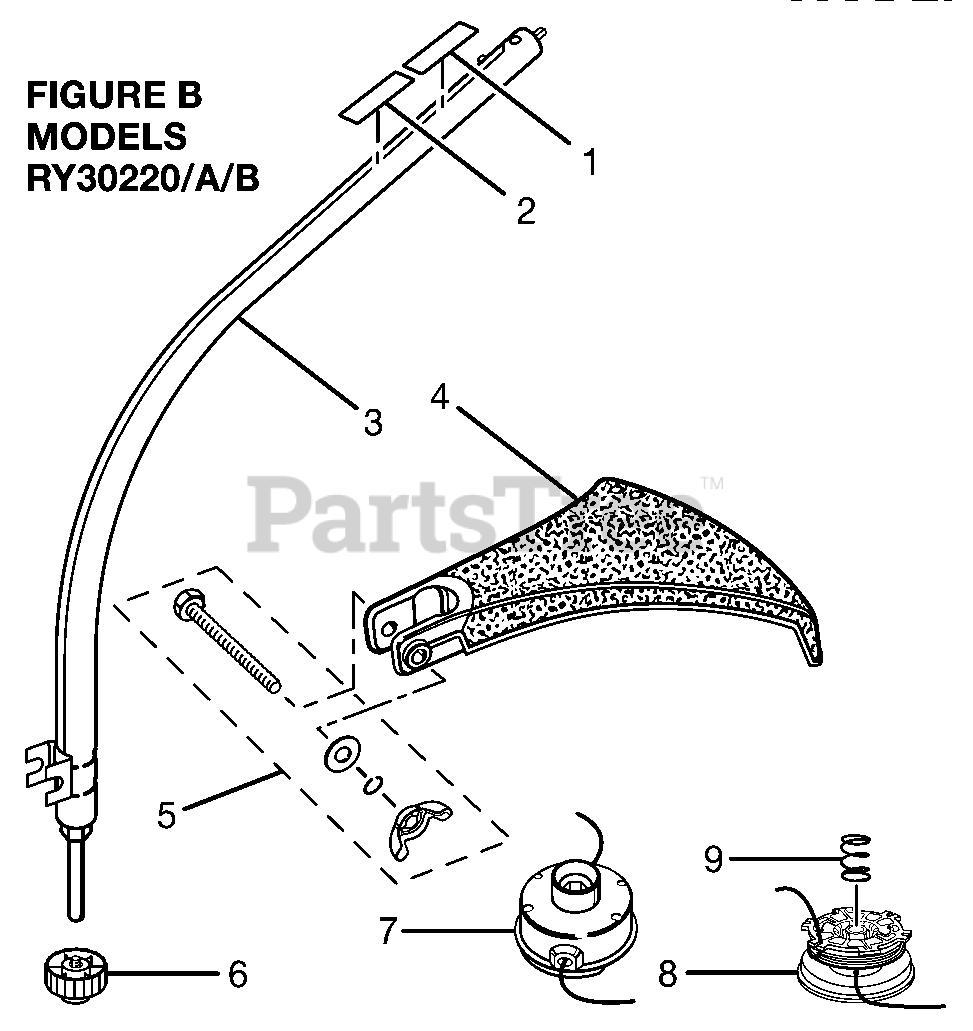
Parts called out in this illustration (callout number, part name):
1	Expand-it Label
2	Warning Decal
3	Curved Shaft Assembly
4	Grass Deflector
5	Fastener Kit
6	Spool Retainer (Black)
7	Complete String Head (.080 in.)
8	Spool and String (.080 in.)
9	Compression Spring
